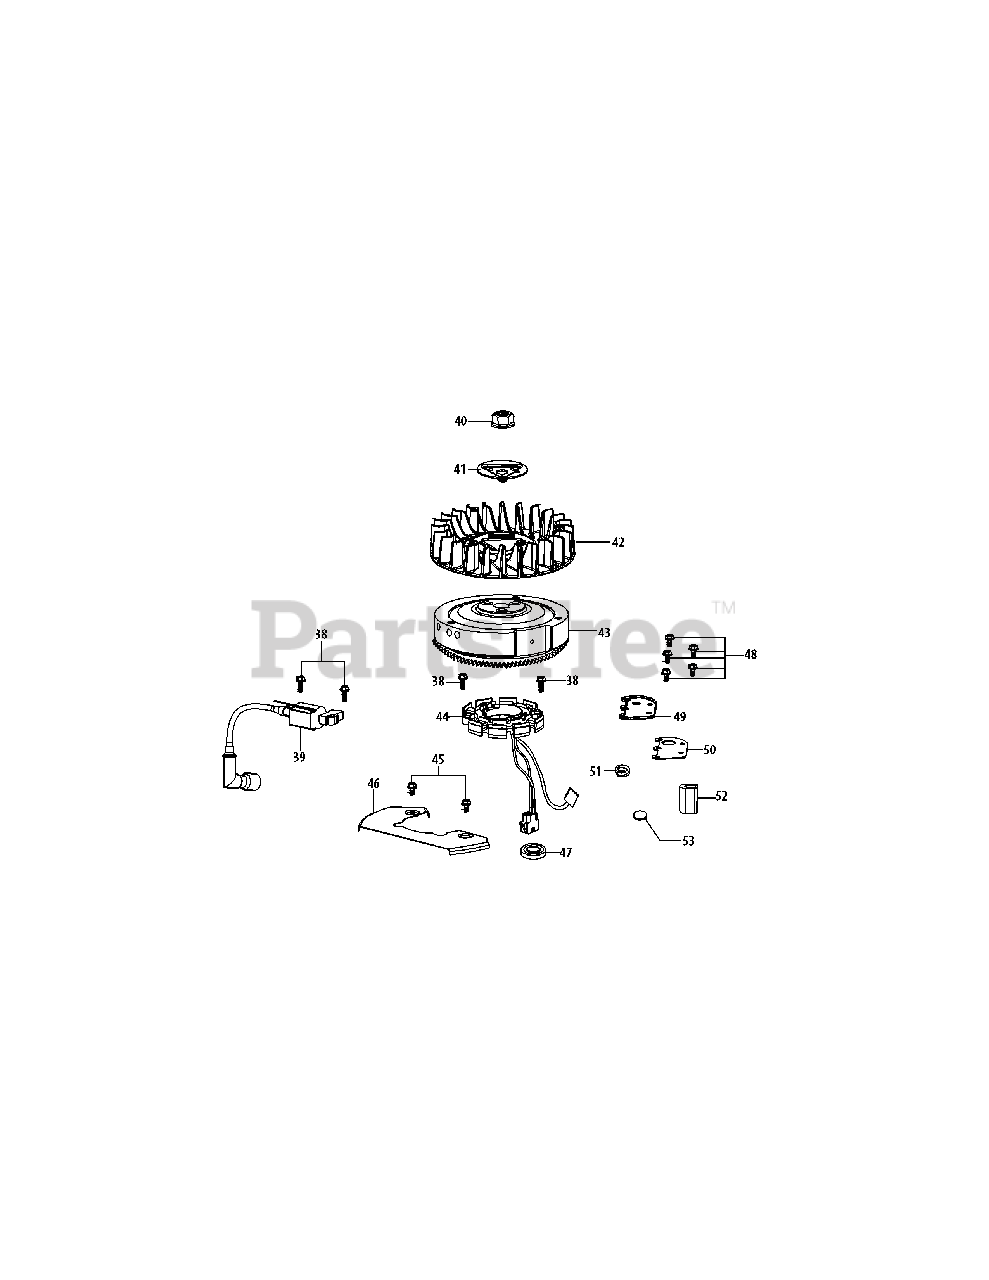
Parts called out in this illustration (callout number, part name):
38	Bolt M6×28
39	Ignition Coil Assembly
40	Flywheel Nut M16×1.5
41	Fan Mounting Plate
42	Cooling Fan
44	Coil Assy.,Charge
45	Bolt M6×10
46	Cowl Cover Shield
47	Lower Crankshaft Seal
48	Bolt M6×14
49	Breather Cover Plate
50	Breather Gasket
51	Breather Spring
52	Mesh Screen Filter
53	Breather Valve
